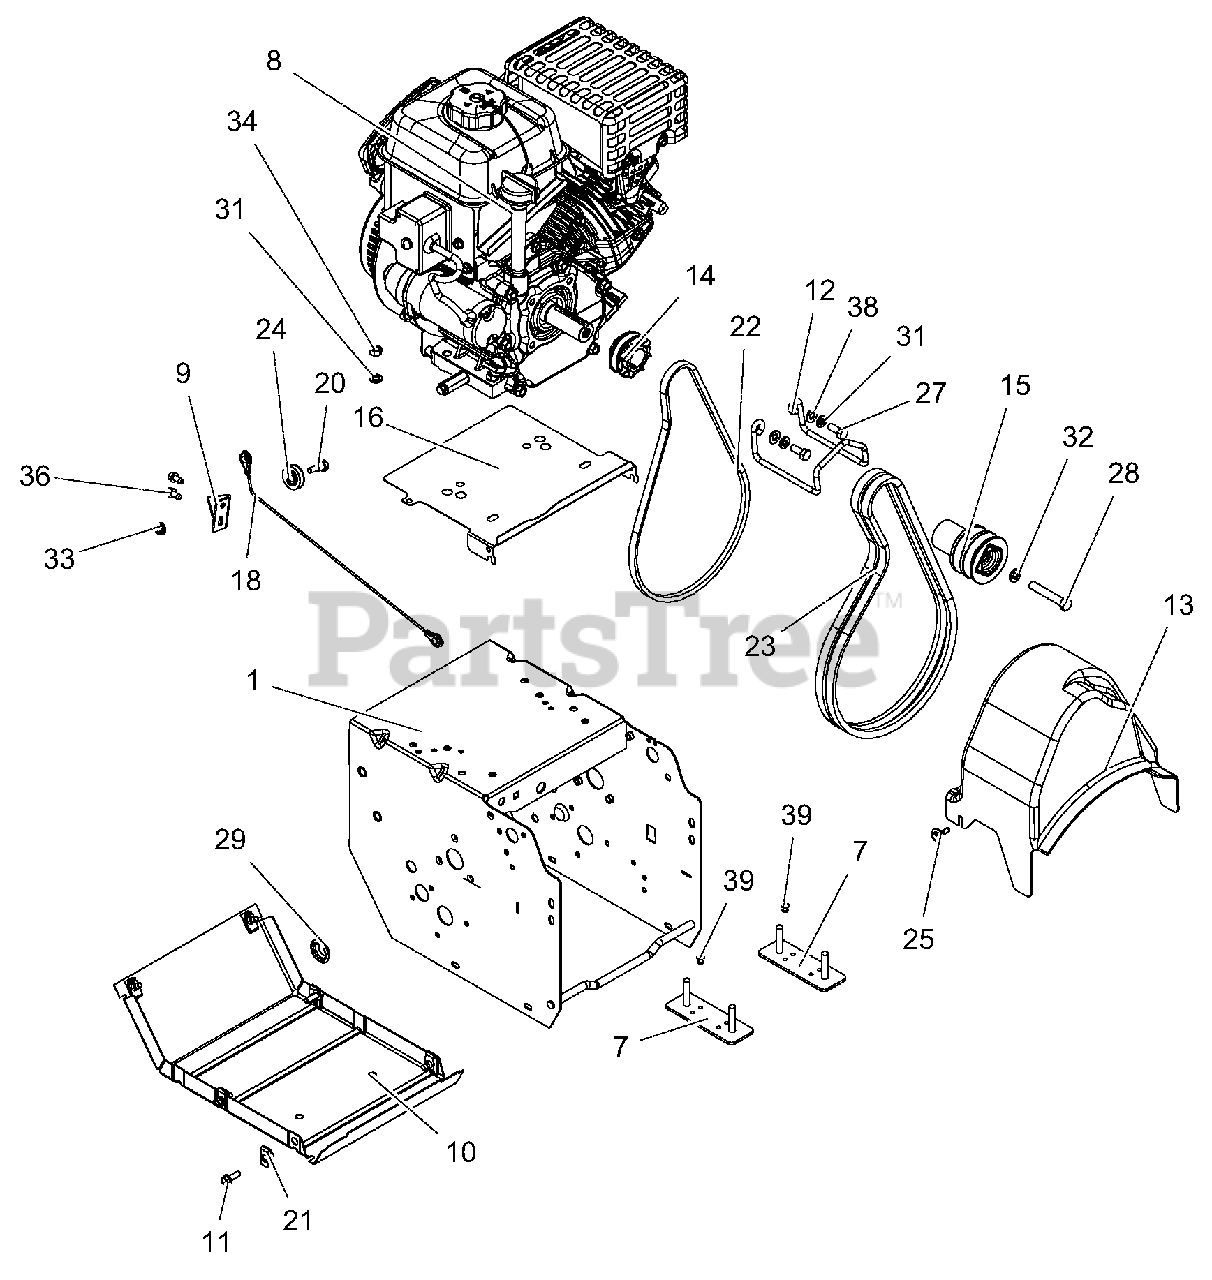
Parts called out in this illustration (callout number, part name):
1	WELDMENT, FRAME - DLX HYBRID
7	STRAP,ENGINE BOLT,ARIENS SML
8	ENGINE, ARIENS AX254 120V/60W
9	BRACKET, CABLE PULLEY
10	COVER, BOTTOM
11	BLT-HEX .25-20X.75 HWH YZ GR5
12	FINGER, BELT
13	BELT COVER
14	SHEAVE, DRIVE
15	SHEAVE,ATTACHMENT 2-GRV
16	BAFFLE,ENGINE,ARIENS SML BLOCK
18	CABLE, LOWER TRACTION (DELUXE)
20	BOLT, SHLDR-.375X.375X.25-20
21	NUT-RTNR .25-20X.56
22	V-BELT, 3L-WRAPPED
23	V-BELT, HA-RAW EDGE (SET)
24	PULLEY, CABLE
25	SCR-TAP .25-20X.5 CAPTIVE
27	BLT-HEX .31-24X.75 YWZC GR5
28	BLT-HEX .38-24X2.25 YWZC GR5
29	PLUG, HOLE - .875" NYLON
31	WSHR-LK .312X.097 HVY YWZC
32	@WSHR-LK .38X.094 REG YWZC
33	@NUT-LK-CTR-FLG .25-20 YWZC
34	@NUT-HEX .31-18 YWZC
36	SCR-TAP .25-20X.50 HWH TR YWZ
38	@WSHR-FL-STL.344X.688X.065YWZC
39	RVT-POP .187 YZ
